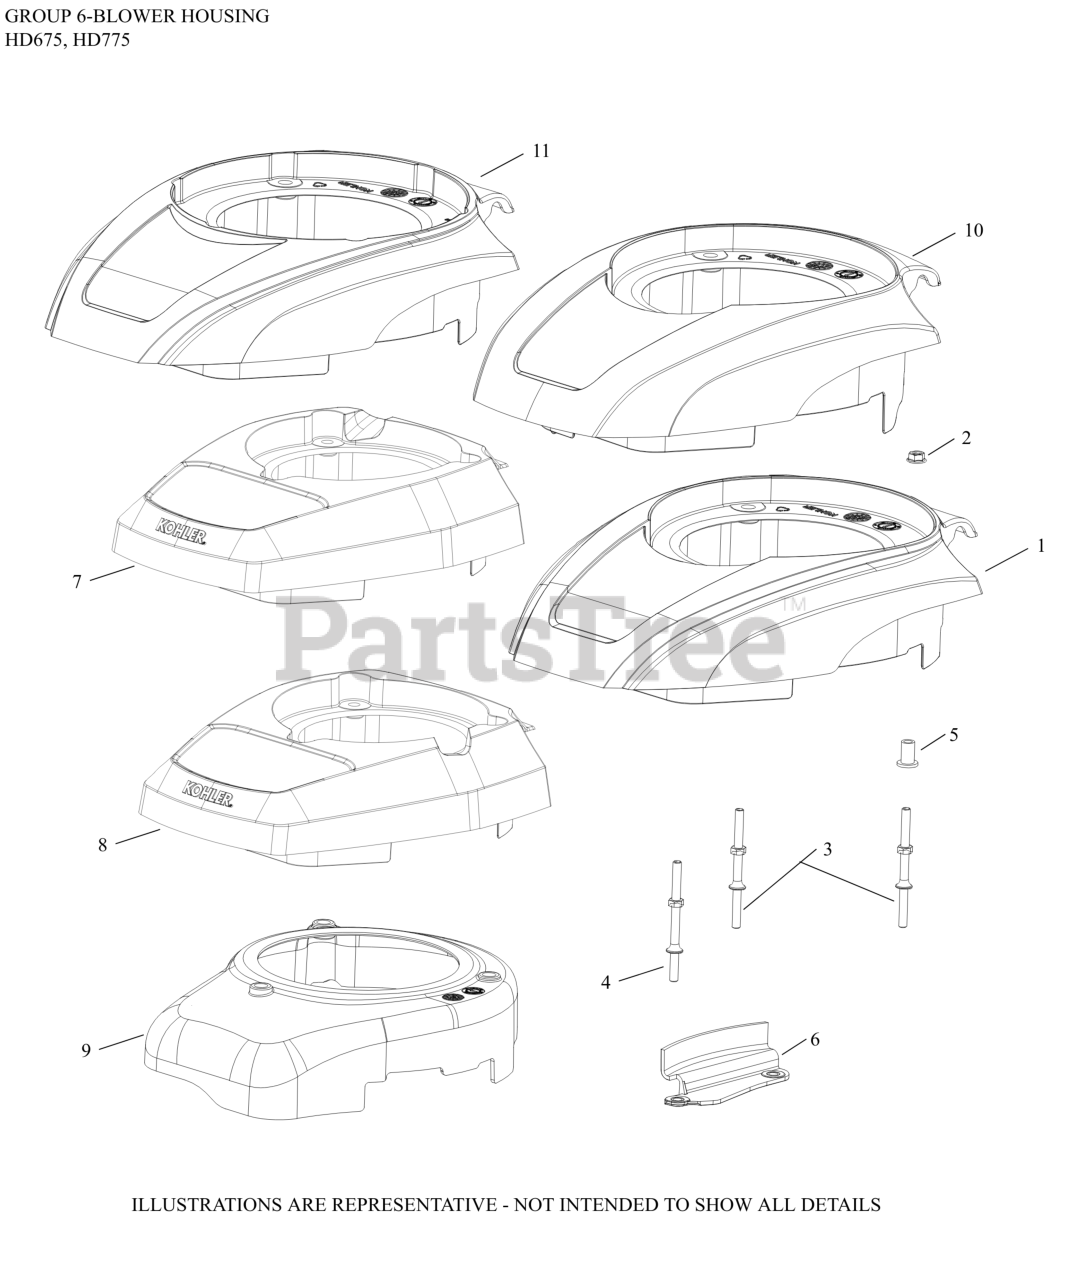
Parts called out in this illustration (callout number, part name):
1	COVER, ENGINE
2	NUT, HEX FLANGE (M6) - USE 14 100 16-S
3	STUD, BLOWER HOUSING (IGNITION)
4	STUD, BLOWER HOUSING (IGNITION)
